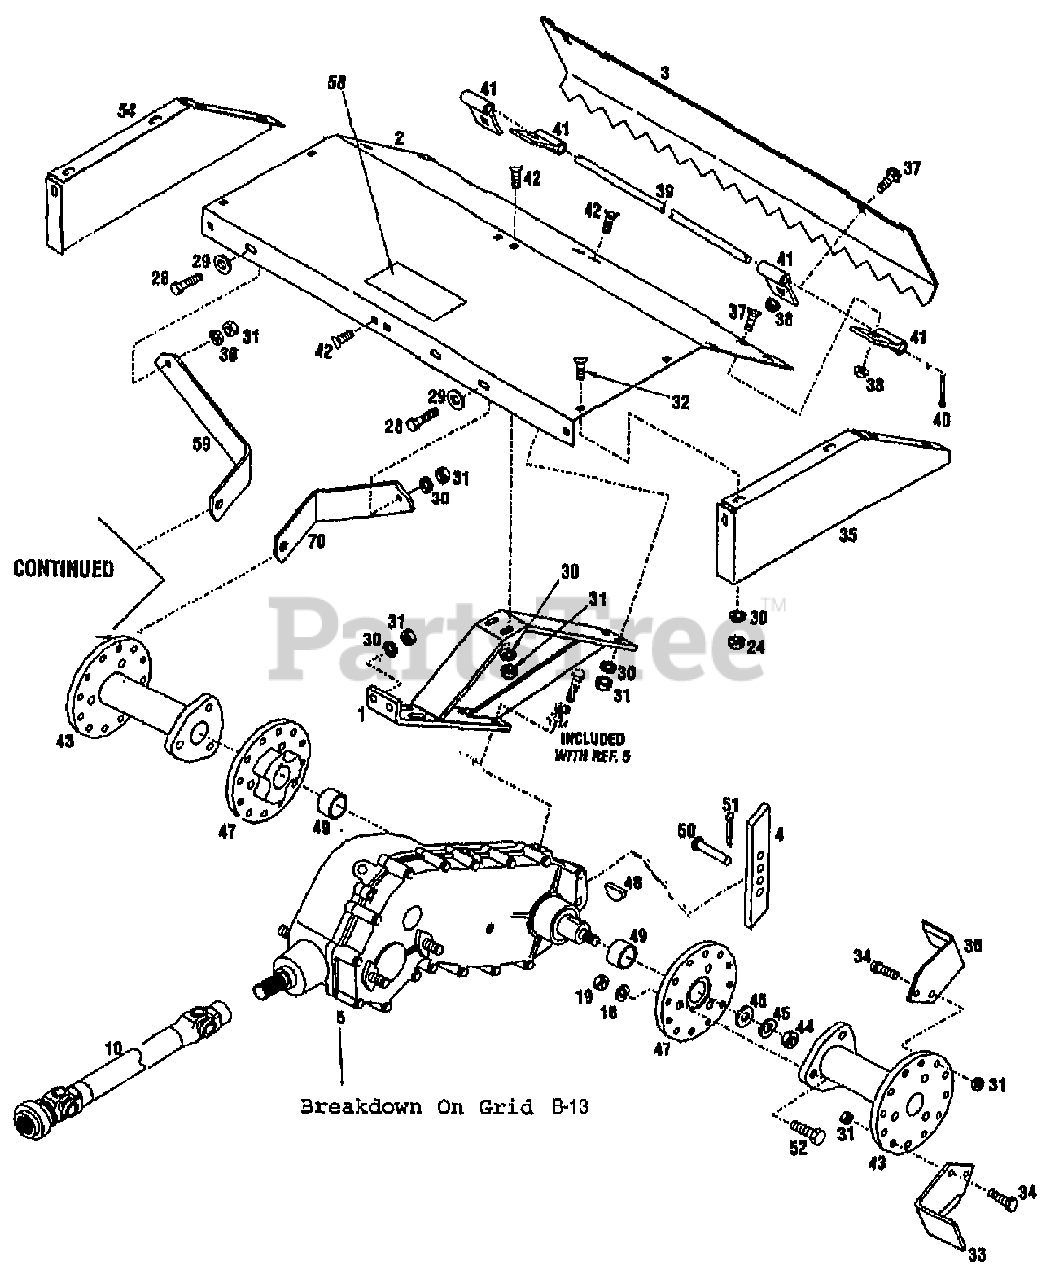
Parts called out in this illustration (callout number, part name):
1	SUPPORT
2	HOOD W/DECALS
3	BOARD-LEVELING
4	SHOE-CENTER
5	ASSM-GEAR CASE
10	SHAFT-DRIVE
18	WASHER-LK .5
19	NUT-HEX JAM 1/2-13
24	NUT-HEX/JAM 3/8-16
28	SCR-HH 3/8-16X1.0 G5 ZP
29	WASHER-FLAT 3/8 SAE
30	WASHER-LK .375 @ DEPL
31	NUT-LOCK 3/8-16
32	SCR-CARR 3/8-16X.75 G5 ZP
34	SCR-HH 3/8-16X1.25
35	HOOD-LH SIDE
37	SCR-CARR 5/16-18X.75
38	NUT-HFLK 5/16-18 ZP
39	PIN-HINGE
40	PIN-COTTER .09X.75 ZP
41	HINGE-HOOD
42	SCR-CARR 3/8-16X1.00
43	SPACER-TINE
45	WASHER-1.41X.656X.18 SPECIAL
46	WASHER-SPACER
48	KEY-WDRF
49	SLEEVE
50	PIN-CLEVIS .5X2.5 ZP
51	PIN-COTTER .120X1.00 ZP
52	SCR-HH 1/2-13X1.75 G5 ZP
54	HOOD-RH SIDE
58	DECAL-OPEI CAUTION
59	BRKT-SUPPORT
70	BRKT-SUPPORT
